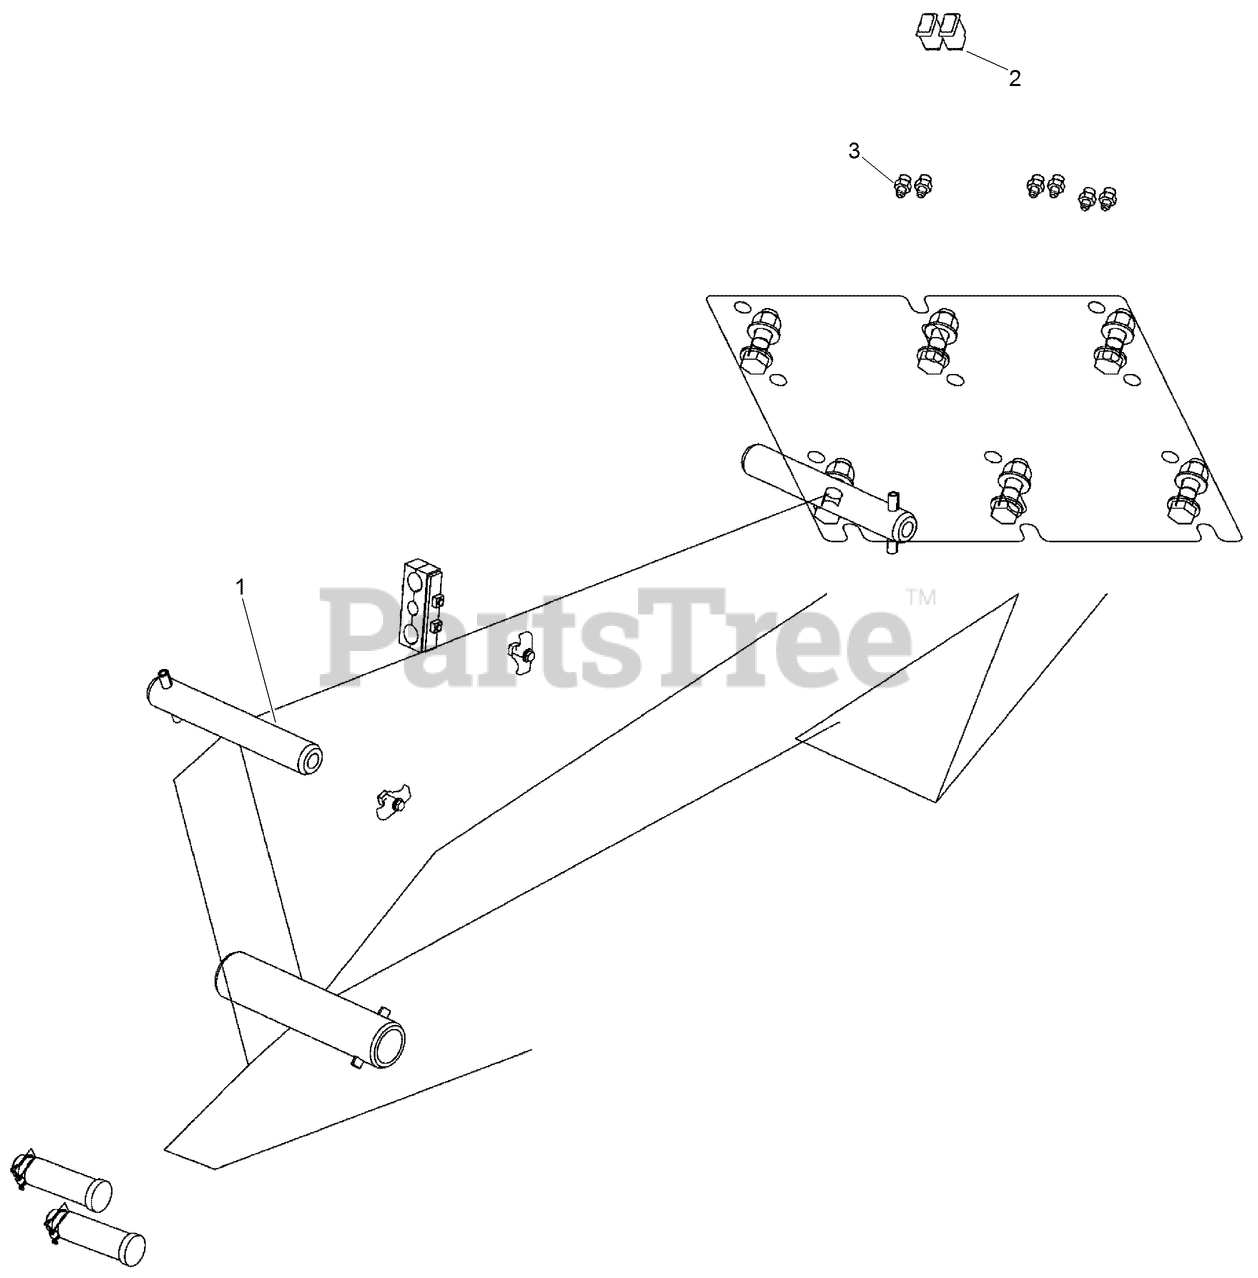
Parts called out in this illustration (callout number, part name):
1	KIT - Attachment, Plow
2	SWITCH-ROCKER, 2 POLE (ON/OFF)
3	CONNECTOR
